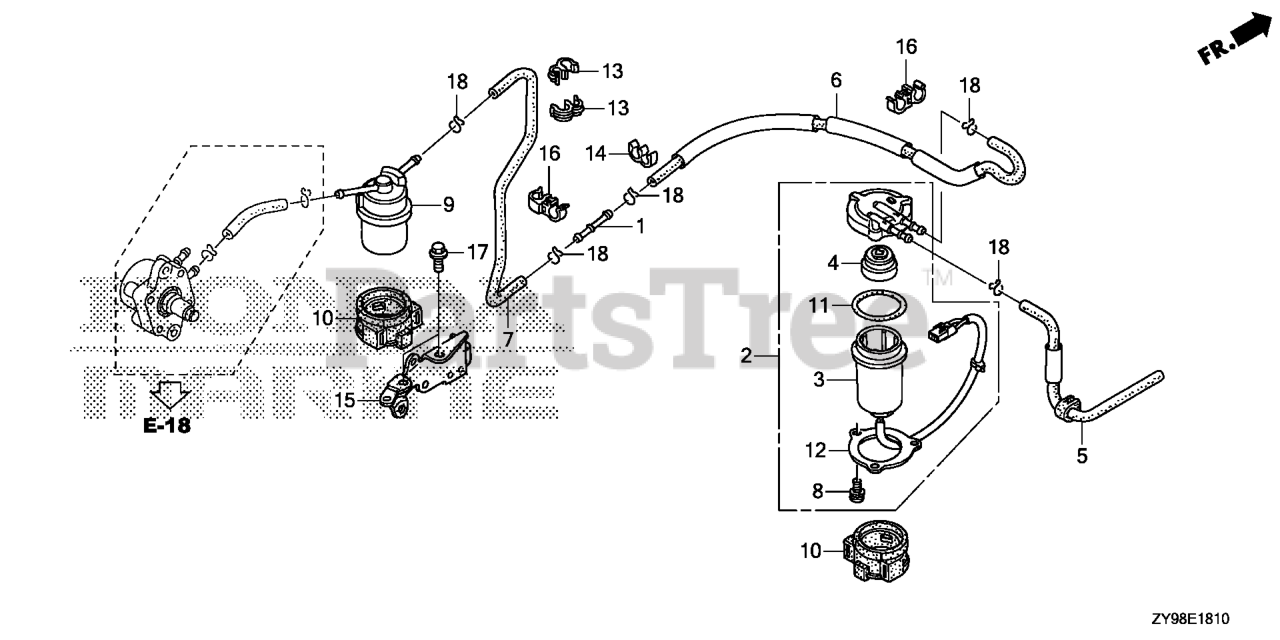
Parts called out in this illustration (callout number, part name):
1	JOINT, FUEL FEED HOSE
2	SEPARATOR ASSY., WATER
3	CUP, WATER SEPARATOR
4	BUFFER, PLATE
5	TUBE A, FUEL
6	TUBE B, FUEL
7	TUBE C, FUEL
8	SCREW, PAN (5X12)
9	FILTER, FUEL
10	SUSPENSION, STRAINER
13	CLAMP, TUBE (7.5-11.5) (BLACK)
14	CLAMP, TUBE
15	BRACKET B, HARNESS CLIP
16	CLIP, SENSOR HOSE
17	BOLT, FLANGE (6X14) (CT200)
18	CLIP, TUBE (B12)
